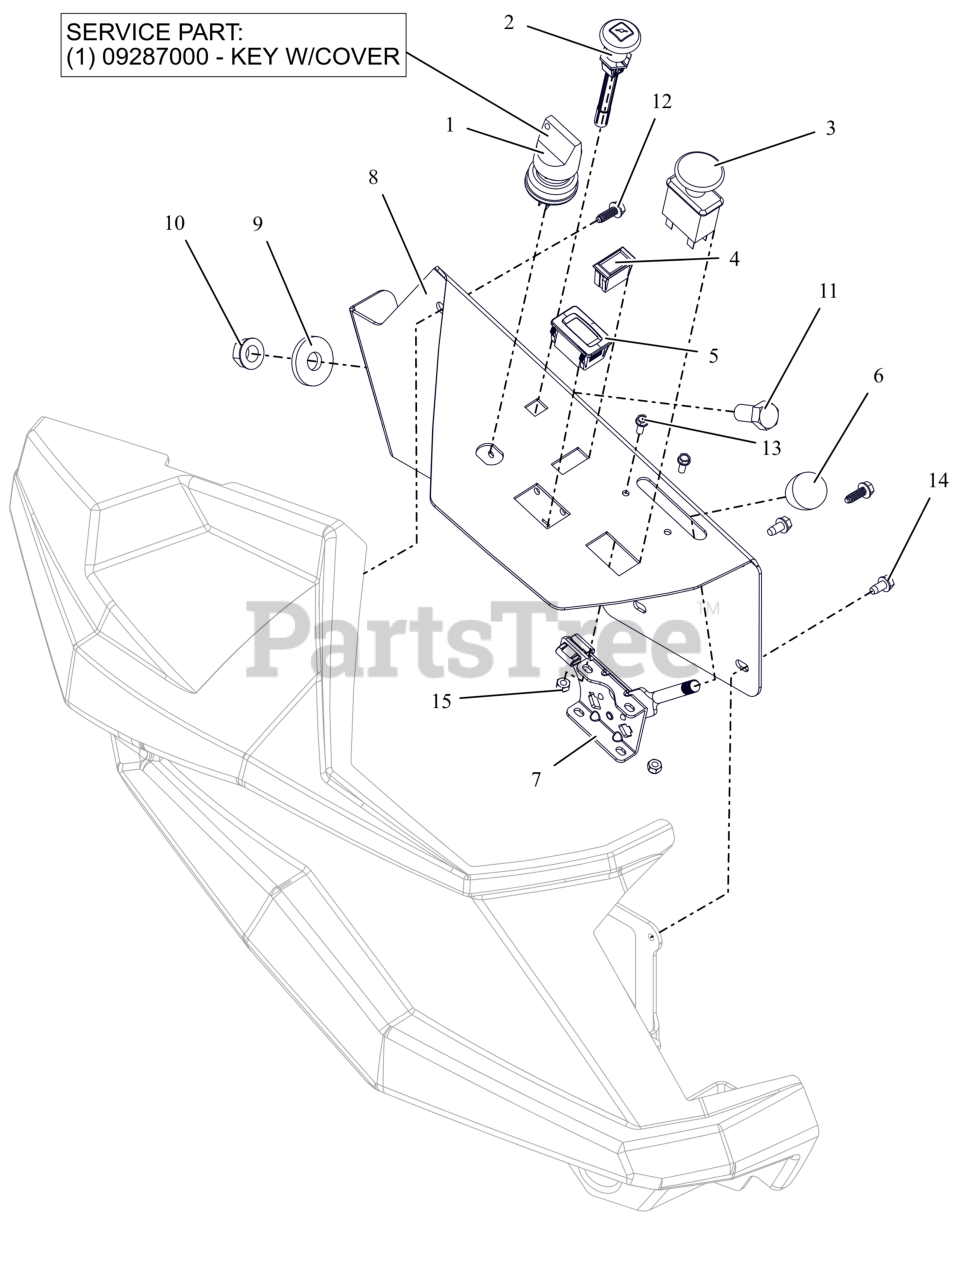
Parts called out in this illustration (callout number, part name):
1	SWITCH, IGNITION
1	KEY, W/ SHIELD
2	CABLE - CHOKE, SNAP-IN
3	SWITCH, CLUTCH
4	SWITCH,BLANK
5	HOUR METER
6	KNOB-CONTROL-BLACK .38-16X.50
7	CABLE, PRO THROTTLE CONTROL
8	PANEL, HD CONTROL (RED)
9	WASHER- FLT .562X1.50X.187 ZCC
10	NUT-LK-TOP-FLG .500-13 GF ZCC
11	BLT, HEX .50-13X1.00 G5 ZCC
12	SCR, PLASTITE-HWH 0.25 X 0.75 ZC120
13	BLT, HWH #10-24X.50 ZCC
14	SCR-TAP .25-20X.50 HWH ZCC
15	NUT-LK-NYL #10-24 G2 ZCC
